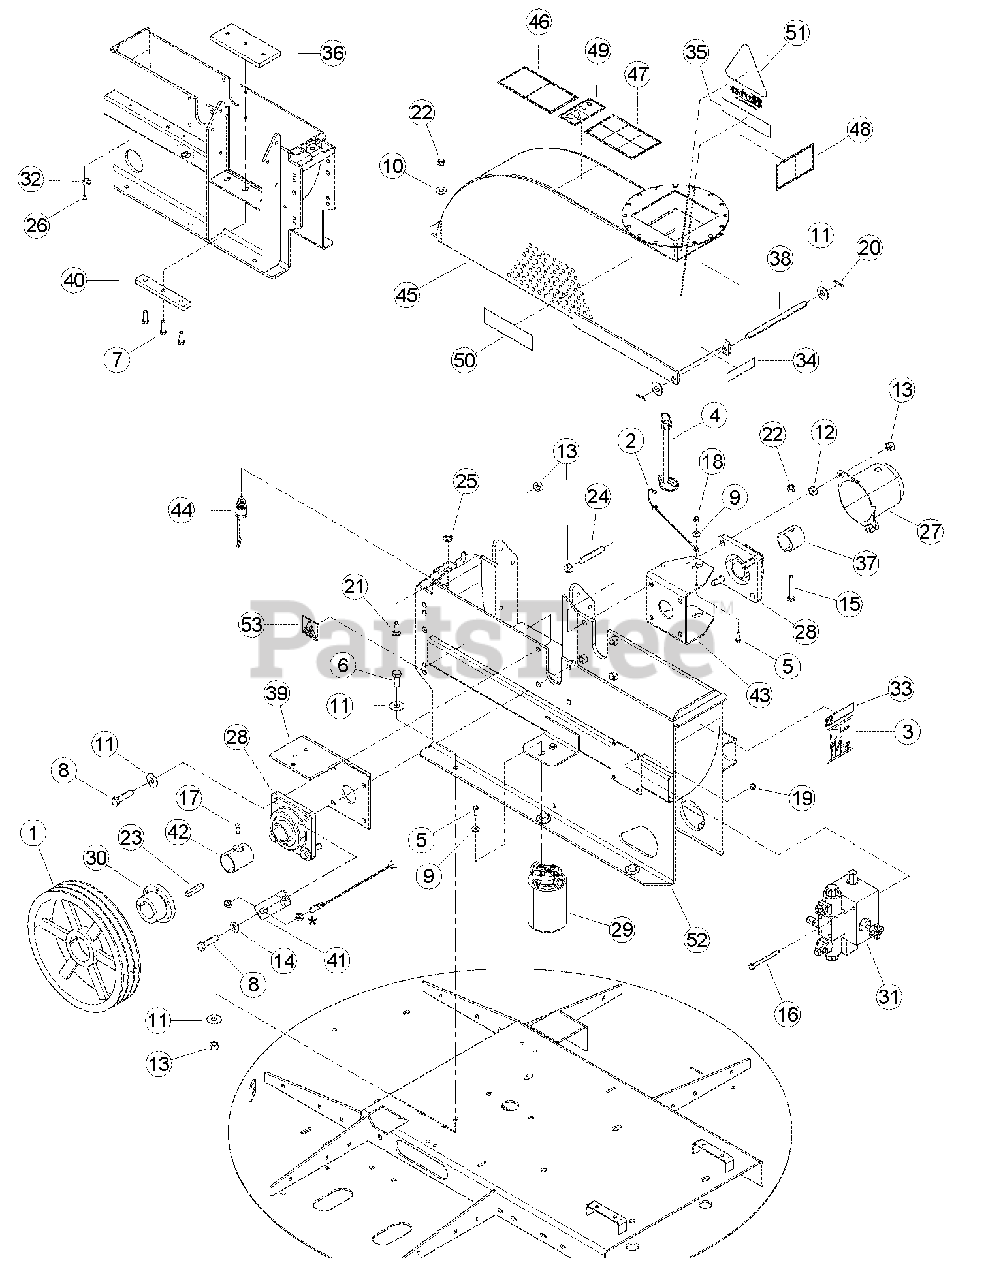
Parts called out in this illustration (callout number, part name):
1	SHEAVE, 3BQ12.4, SK
2	LANYARD, NYLON
3	DECAL, 114 DB (CE COMPLIANT MODELS)
4	PIN, HITCH 1/2 X 6-1/2 W LYNCH
5	BOLT, 1/4 X 3/4 HEX HD GR5 ZP
6	BOLT, 1/2 X 1-1/4 HEX HD GR5 NC ZP
7	BOLT, 1/2 X 1-1/2 HEX HD GR5 ZP
8	BOLT, 1/2 X 2 HEX HD GR5 ZP
9	WASHER, 1/4 FLAT ZP
10	WASHER, 3/8 FLAT ZP
11	WASHER, 1/2 FLAT ZP
12	NUT, 1/2 HEX NC ZP
13	NUT, 1/2 CENTERLOCK GRB ZP
14	WASHER, 1/2 SAE FLAT ZP
15	BOLT, 3/8 X 2-1/2 HEX HD GR5 ZP
16	BOLT, 5/16 X 3-1/2 HEX HD ZP
17	SCREW, 5/16-18 X 5/8 SQ HD SET
18	NUT, 1/4 NE NYLOCK ZP
19	NUT, 5/16 NE NYLOCK ZP
20	PIN, 1/8 X 1.00 ZP COTTER
21	BOLT, 3/8 X 1-1/4 CRG GR5 NC ZP
22	NUT, 3/8 NE NYLOCK ZP
23	KEY, 3/8 SQUARE X 2 LONG PLAIN
24	STUD, 1/2-13 X 3 B7 ZP
25	NUT, 5/8 JAM
26	RIVET, AL BLIND 1/4 X 3/4 DOME HEAD
27	CAP, LARGE SHAFT
28	BEARING, 1-3/4" 4 BOLT FLANGE
29	FILTER, SPIN-ON
30	BUSHING, SK 1-3/4"
31	ASSEMBLY, CHIPPER VALVE
32	CLAMP, CABLE MOUNT
33	DECAL, 76824 INFORMATION (CE COMPLIANT MODELS)
34	DECAL, ATLANTIC BRIDGE LTD INFO (CE COMPLIANT MODELS)
35	DECAL, MODEL CH8720IH
36	PLATE, CHIPPER BOTTOM
37	COLLAR, CHIPPER LOCK
38	SHAFT, CHIPPER TOP PIVOT
39	WELDMENT, REAR GUARD SUPPORT
40	SPACER, CHIPPER ANVIL
41	BRACKET, PROXIMITY SENSOR
42	WELDMENT, SPACER 2.0 X 2.30
43	BRACKET, DISK LOCK
44	ASSEMBLY, SEALED SWITCH
45	ASSEMBLY, CHIPPER TOP HOUSING, SERVICE PART (INCLUDES ITEMS 46 - 51)
46	DECAL, KNIFE ACCESS ISO
47	DECAL, OPERATING INSTRUCTIONS
48	DECAL, DISCHARGE ISO
49	DECAL, MAINTENANCE ISO
50	DECAL, ECHO BEARCAT 6.82 X
51	DECAL, CHIP IT
52	ASSEMBLY, CHIPPER BOTTOM, SERVICE PART (INCLUDES ITEM 53)
53	DECAL, SHIELD DANGER ISO
